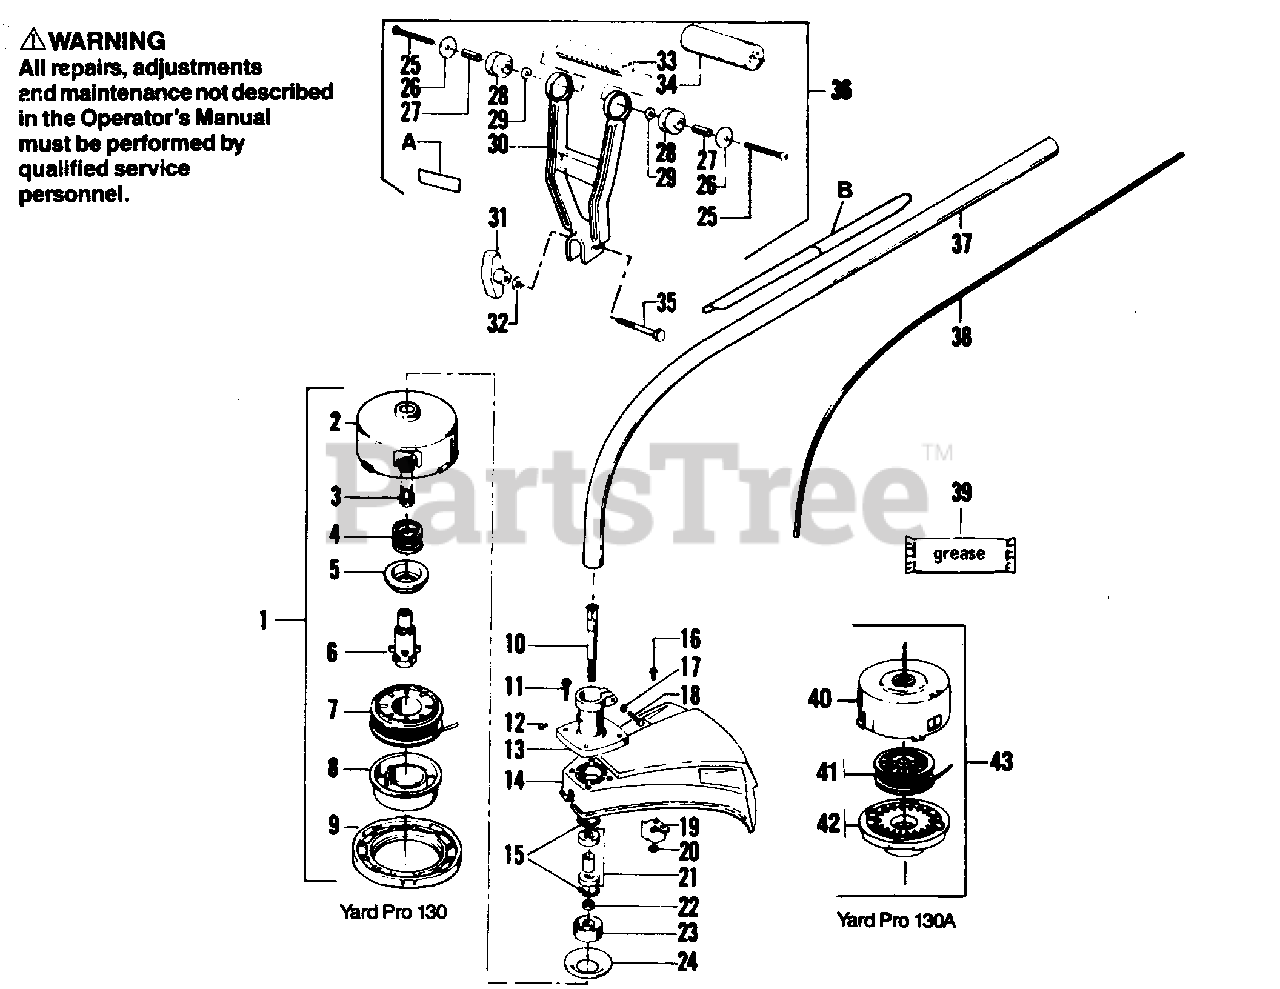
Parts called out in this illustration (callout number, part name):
1	Cutting Head Ass'y (Incl. #2-9)
2	Hub w/Line Saver
3	Line Saver
4	Spring
5	Adaptor - Spring
6	Drive Gear
7	Spool w/Line
8	Release Button
10	Shaft - Arbor
11	Screw - 1/4 - 10 x 1-1/8 - Shield to Bearing Housing
12	Screw - 10-16 x 1/4 - Self - Tapping
15	Retainer - Bearing
16	Screw - 10 - 24 x 5/8 - Hex Hd. - Line Limiter
17	Washer - 1/4 Int. Tooth Lock
18	Screw - Pinch Clamp - 1/4-20 x 1
20	Nut - 10 - 24 - Locking
21	Bearings & Spacer Kit
22	Washer - 3/8 - Dust Cup
23	Dust Cup
25	Screw - Pan Hd. - #12-11 x 2"
26	Cup - Isolator
27	Spacer Isolator
28	Isolator - Handle
29	Washer - 1/4 Flat
30	Handle - Anti-vibe
31	Knob - 1/4 - 20
32	Washer - 1/4 Flat
33	Center Section - Handle
34	Cushion - Handle Center Section
36	Handle - Anti-vibe Assembly (Inc. #25-30, 33, & 34)
37	Drive Shaft Housing
38	Flexible Drive Shaft
39	Flex Shaft Lube
40	Hub Ass'y.
41	Spool w/Line
43	Cutting Head Ass'y. (Incl. #40-42)
A	Decal - Anti-Vibe
